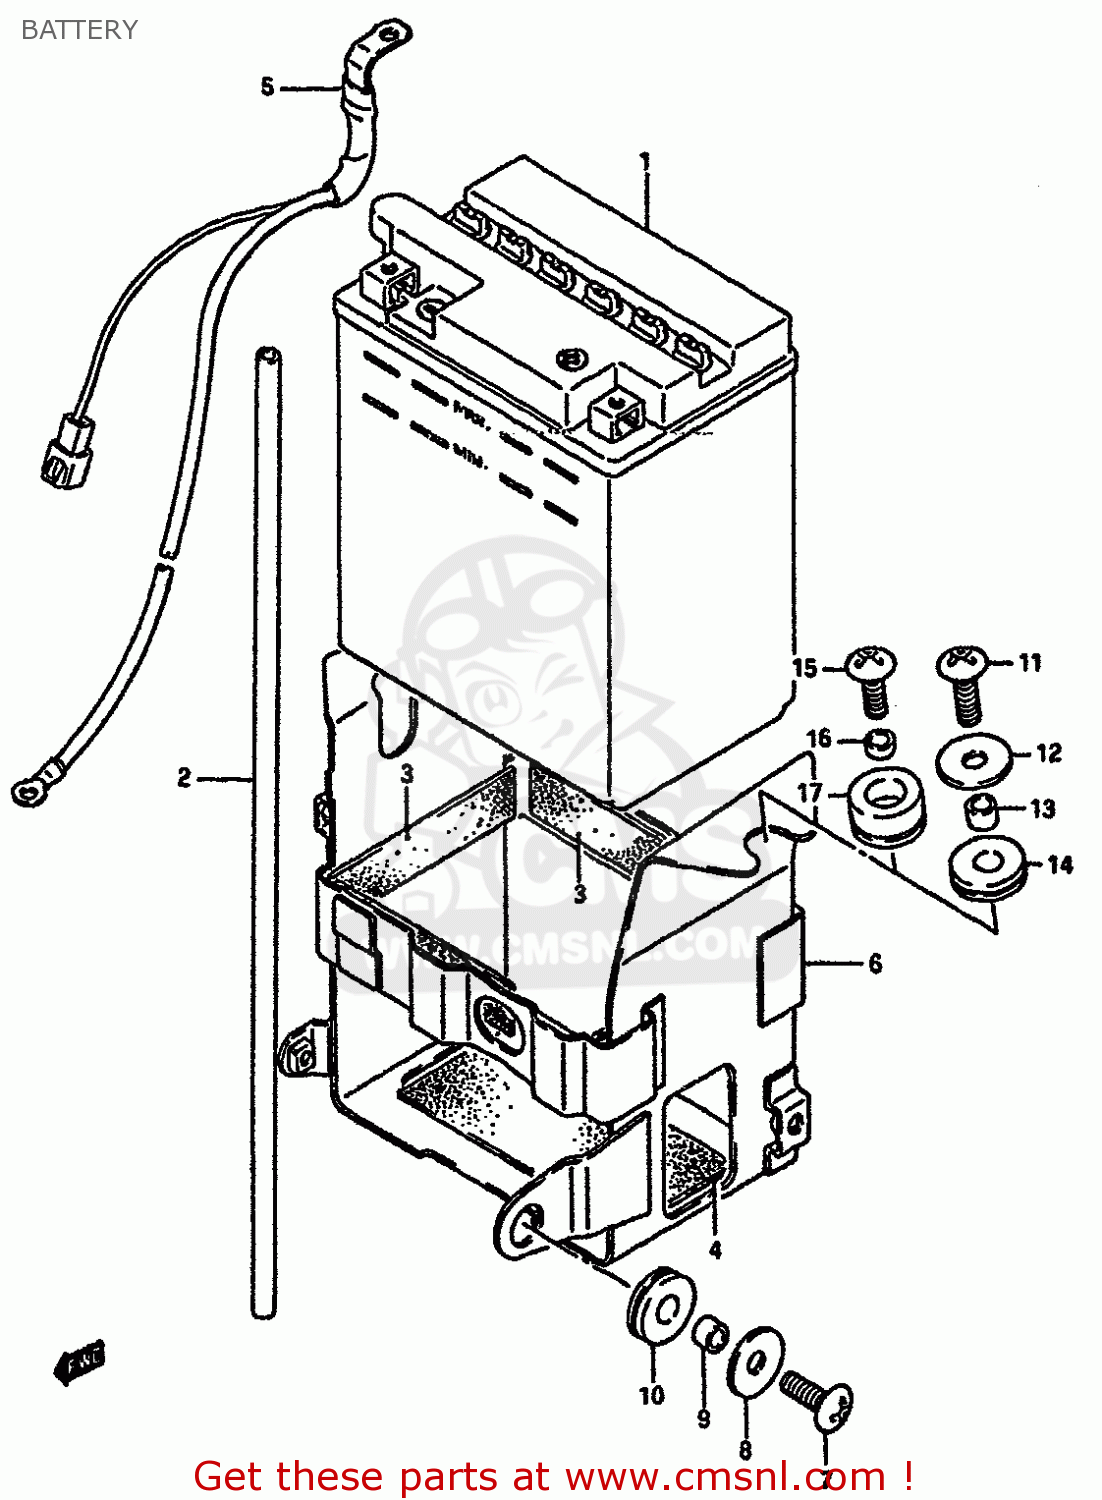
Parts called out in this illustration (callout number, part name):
1	BATTERY ASSY (12V)
2	HOSE,BATTERY EXHAUST
3	PROTECTOR,20X9
4	CUSHION
5	WIRE,BATTERY MINUS LEAD
6	HOLDER,BATTERY
7	SCREW
8	WASHER
9	SPACER
10	CUSHION
11	SCREW
12	WASHER (6.5X24X1.6)
13	SPACER
14	CUSHION
15	SCREW
16	SPACER
17	CUSHION,HOLDER BATTERY UPR
